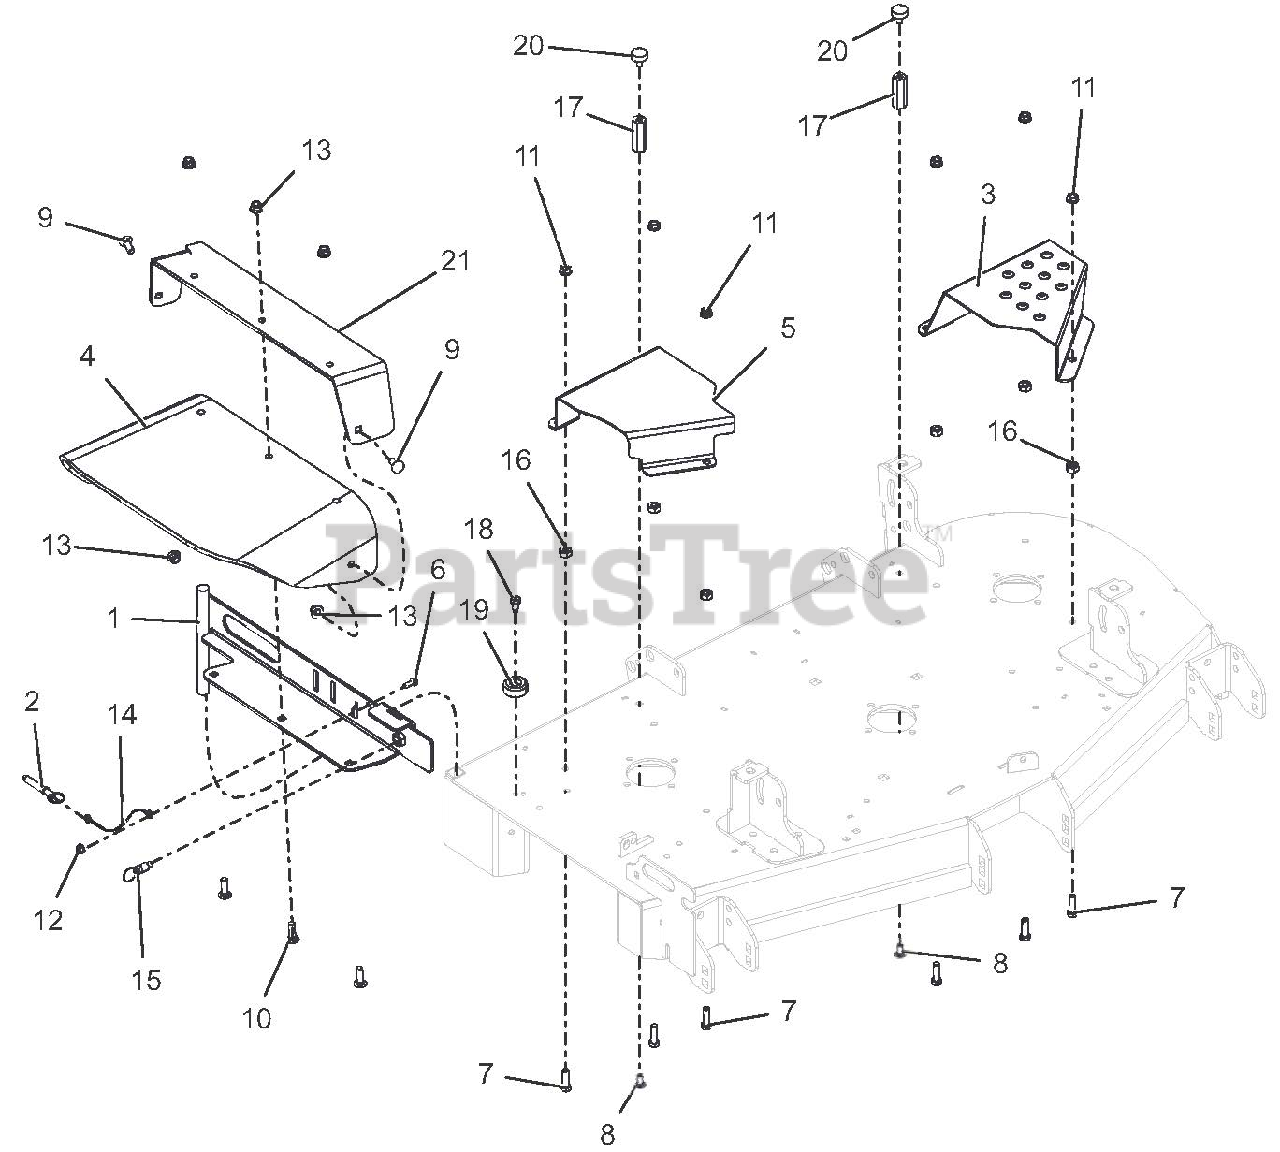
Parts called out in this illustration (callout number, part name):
1	WLDMT, 44" - 48" DISCH CHUTE MTG-RED
2	PIN, SPRING BALL .375 X OD X 1.50
3	GUARD, 44-52" LH DECK BELT - BLACK
4	CHUTE, RUBBER DISCHARG
5	GUARD, 48" - 52" RH DECK BELT - BLACK
6	BLT-HEX .25-20X.75 GR5 YWZC
7	BLT-HEX .38-16 X 1.25 GR5 YWZC
8	BLT, RDHDSQNK .31-18 X .75 LOCTITE
9	BLT-RDHDSQNK .38-16 X 1.00 G5 YWZC
10	BLT-RDHDSQNK .31-18 X 1.25 G5 YWZC
11	@NUT-SPNLK-FLG .375-16 YWZC
12	NUT, LK-TOP-FLG .25-20 YWZC
13	NUT-LK-NYL-FLG .38-16 YWZC
14	CABLE, 6.0 LANYARD, NYLON
15	PULL PIN, .50-13THDX .310 PLNGR
16	NUT-HEAVY HEX .38-16 YWZC
17	NUT, .31-18 X 2.25 LG COUPLING
18	SCR-TAP .31-18 X .75 HWH TR YWZ
19	BUMPER, RECESSED 1.50 X .63 W/ .31 HOLE
20	BUMPER, RUBBER
21	DISCHARGE CHUTE SUPPORT W/ SAFETY DECAL - RED
